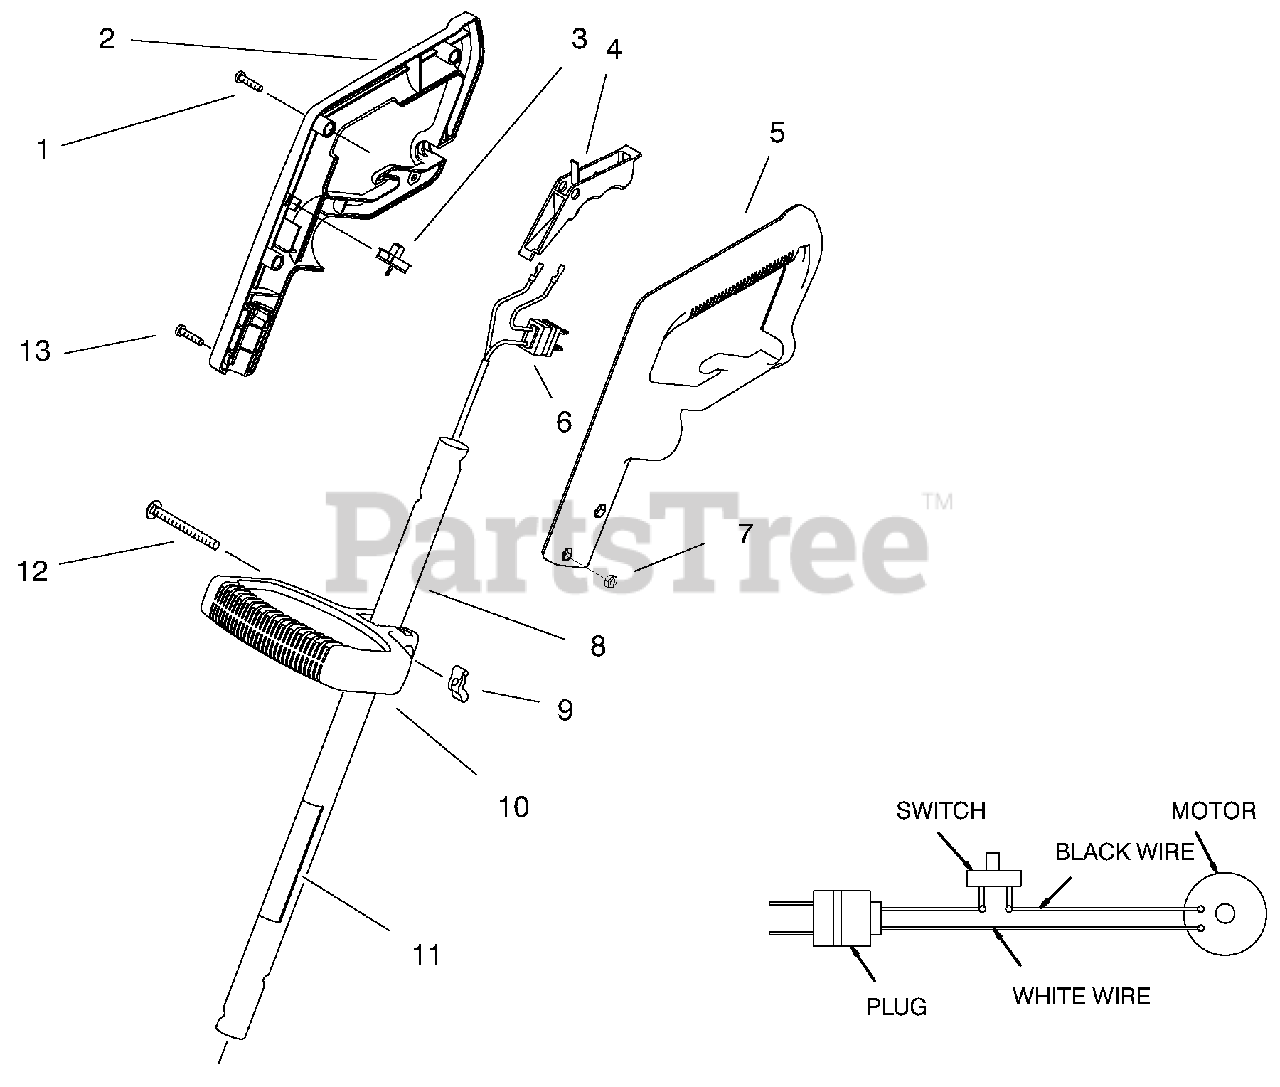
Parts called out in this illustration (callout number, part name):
2	Grip-Hand R.H.
3	Switch-Single Speed
5	Grip-Hand L.H.
6	Harness-Wire
7	Nut-Lock
8	Tube Assembly (Incl. Ref. #11)
10	Handle-Mid
11	Decal-Safety
12	Screw-Carriage
13	Screw-Pan Hd.
